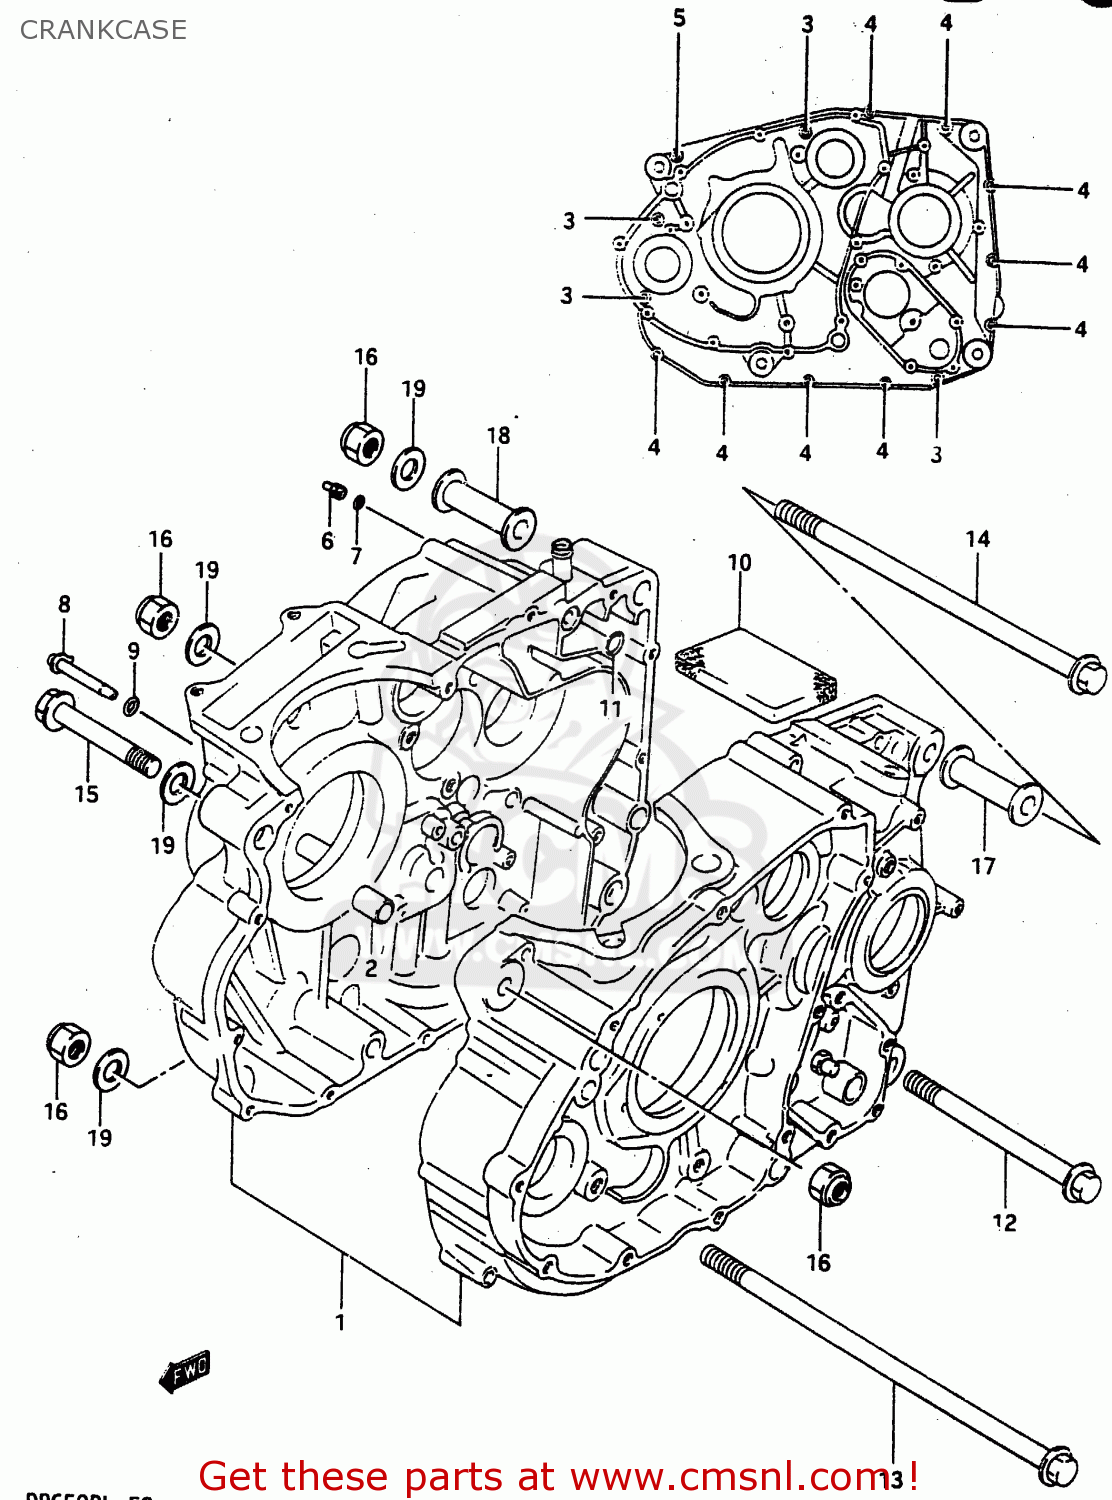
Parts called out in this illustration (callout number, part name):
1	CRANKCASE SET
2	PIN
3	BOLT (6X60)
4	BOLT 6X40
5	BOLT 6X30
6	JET(12)
7	O RING(D:1.2,ID:4)
8	PIPE,PISTON COOLING
9	O-RING
10	SEPARATOR,OIL BREATHER
11	O-RING
12	BOLT
13	BOLT
14	BOLT
15	BOLT
16	NUT (10MM)
17	SPACER,ENG MTG(L:55)
18	SPACER,ENGINE MOUNT(L:65)
19	WASHER 10MM
